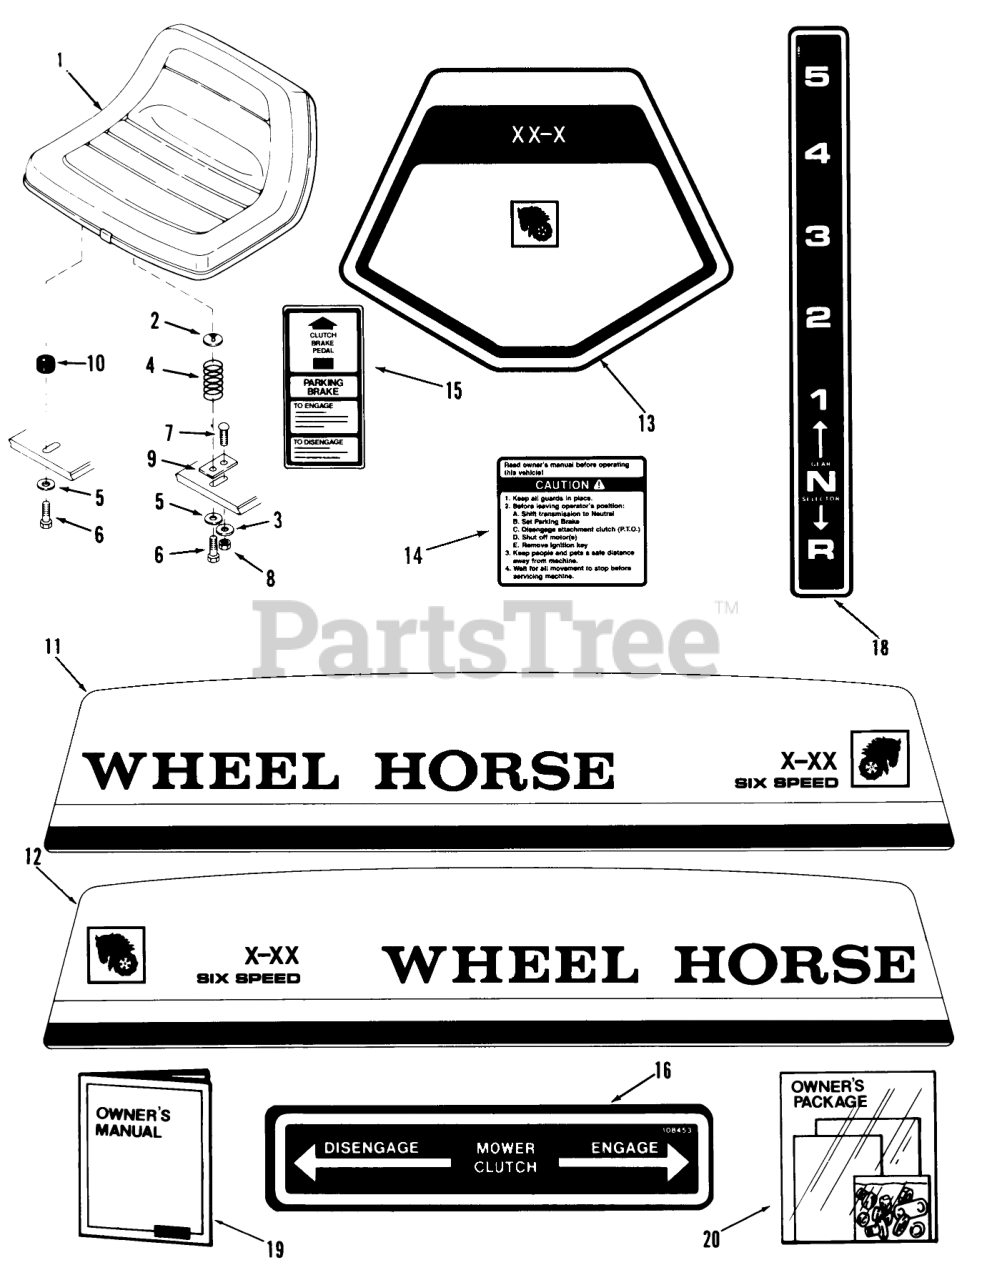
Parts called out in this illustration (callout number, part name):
1	ASSY-SEAT
2	NUT-PUSH
3	Washer
4	SPRING
5	WASHER 5/16 SAE
6	SPECIAL BOLT
6	HHCS
7	CARRIAGE BOLT -4
8	Nut
9	Plate Seat
10	GROMMET-RUBBER
11	Decal-Hood A-81 RH
11	DECAL-SIDE A-111
12	Decal-Hood A-81 LH
12	Rubber Plate
13	Decal-Shroud A-81
13	Decal-Shroud A-111
14	DECAL-CAUTION
15	Decal-Parking Brake
16	Decal-PTO
18	DECAL-SHIFT
19	Owner-s Manual (Rider)
20	New Rider Loose Parts Pkg A-81 (23-08BX01 & 23-08BP02)
20	New Rider Loose Parts Pkg A-81 (03-08BP03)
20	New Rider Loose Parts Pkg A-111 (23-11BP02)
